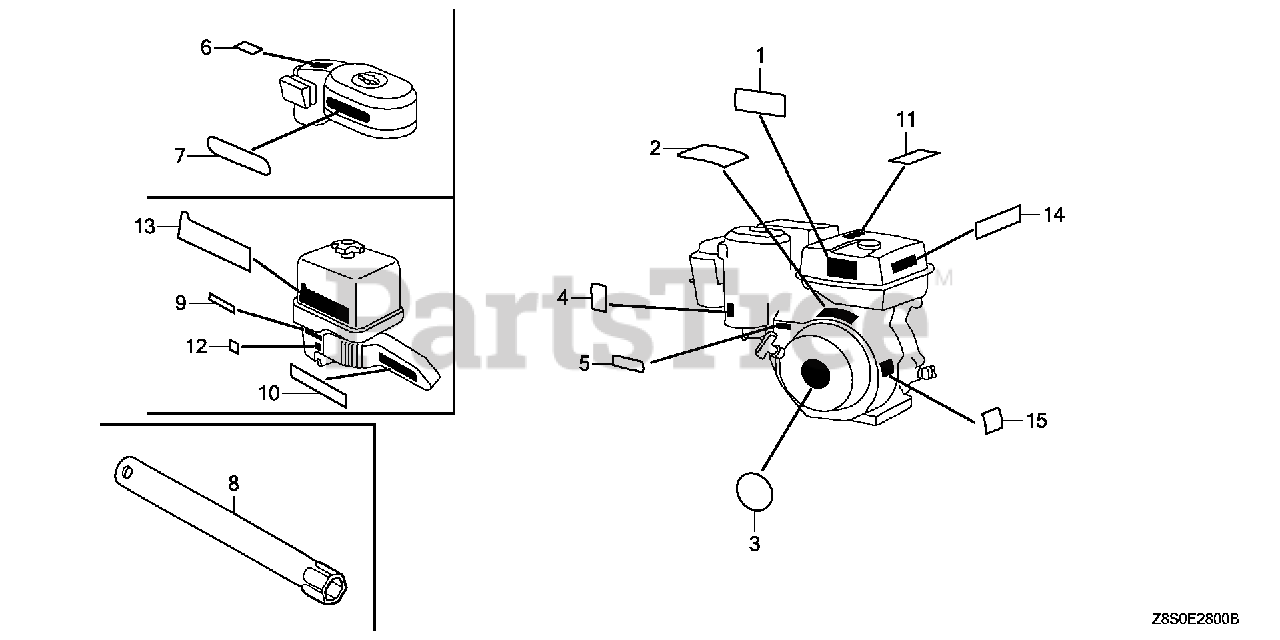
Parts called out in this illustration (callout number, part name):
8	WRENCH, SPARK PLUG
9	MARK, CHOKE
10	MARK, HONDA
11	MARK, EX. CAUTION (ENGLISH)
12	MARK, FUEL
13	MARK, SALES POINT
14	MARK, OPERATOR CAUTION (ENGLISH)(MADE IN THAI)
